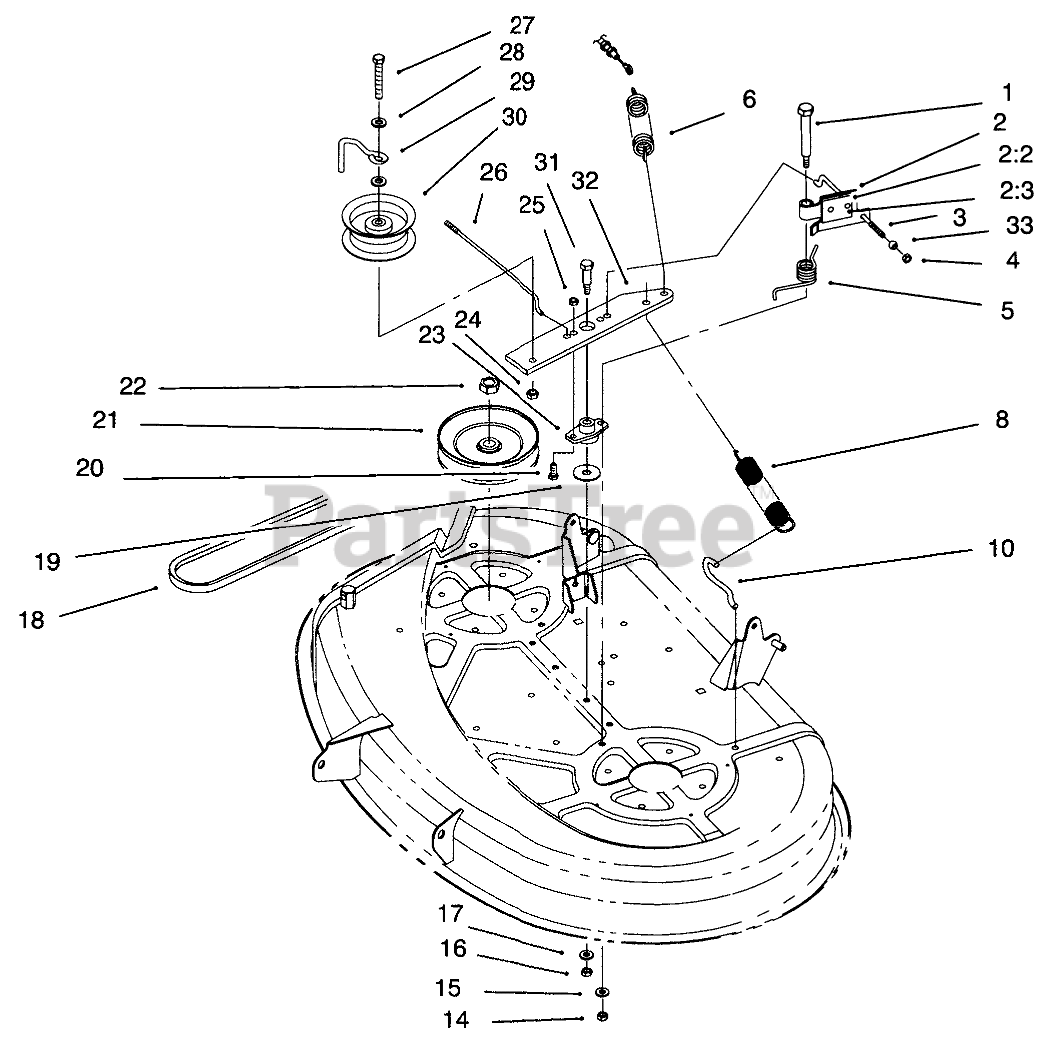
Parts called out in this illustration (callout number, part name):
1	BOLT-SHOULDER
2	ASM.-Deck Brake (Incl. Ref. #2:2-2:3)
2:2	PAD-BRAKE
2:3	RIVET-BLIND
3	ROD-BRAKE, DECK LH
4	NUT-LOCK, NI
5	SPRING-TORSION
6	SPRING-DECK, ENGAGEMENT
8	SPRING-EXTENSION
10	HOOK-RETURN, SPRING
14	NUT-LOCK, NI
15	WASHER-PLAIN
16	NUT-LOCK, NI
17	WASHER-PLAIN
18	BELT-V
19	WASHER-FLAT
20	SCREW-HH
21	PULLEY
22	NUT-HEX
23	BUSHING-ARM, IDLER
24	NUT-LOCK, NI
25	NUT-LOCK, NI
26	ROD-BRAKE, DECK RH
27	SCREW-HH
28	WASHER-FLAT
29	GUIDE-IDLER, BELT
30	PULLEY-IDLER, FLAT
31	SCREW-SHOULDER, HH
32	ARM-IDLER
33	BALL-SWIVEL, STOP
